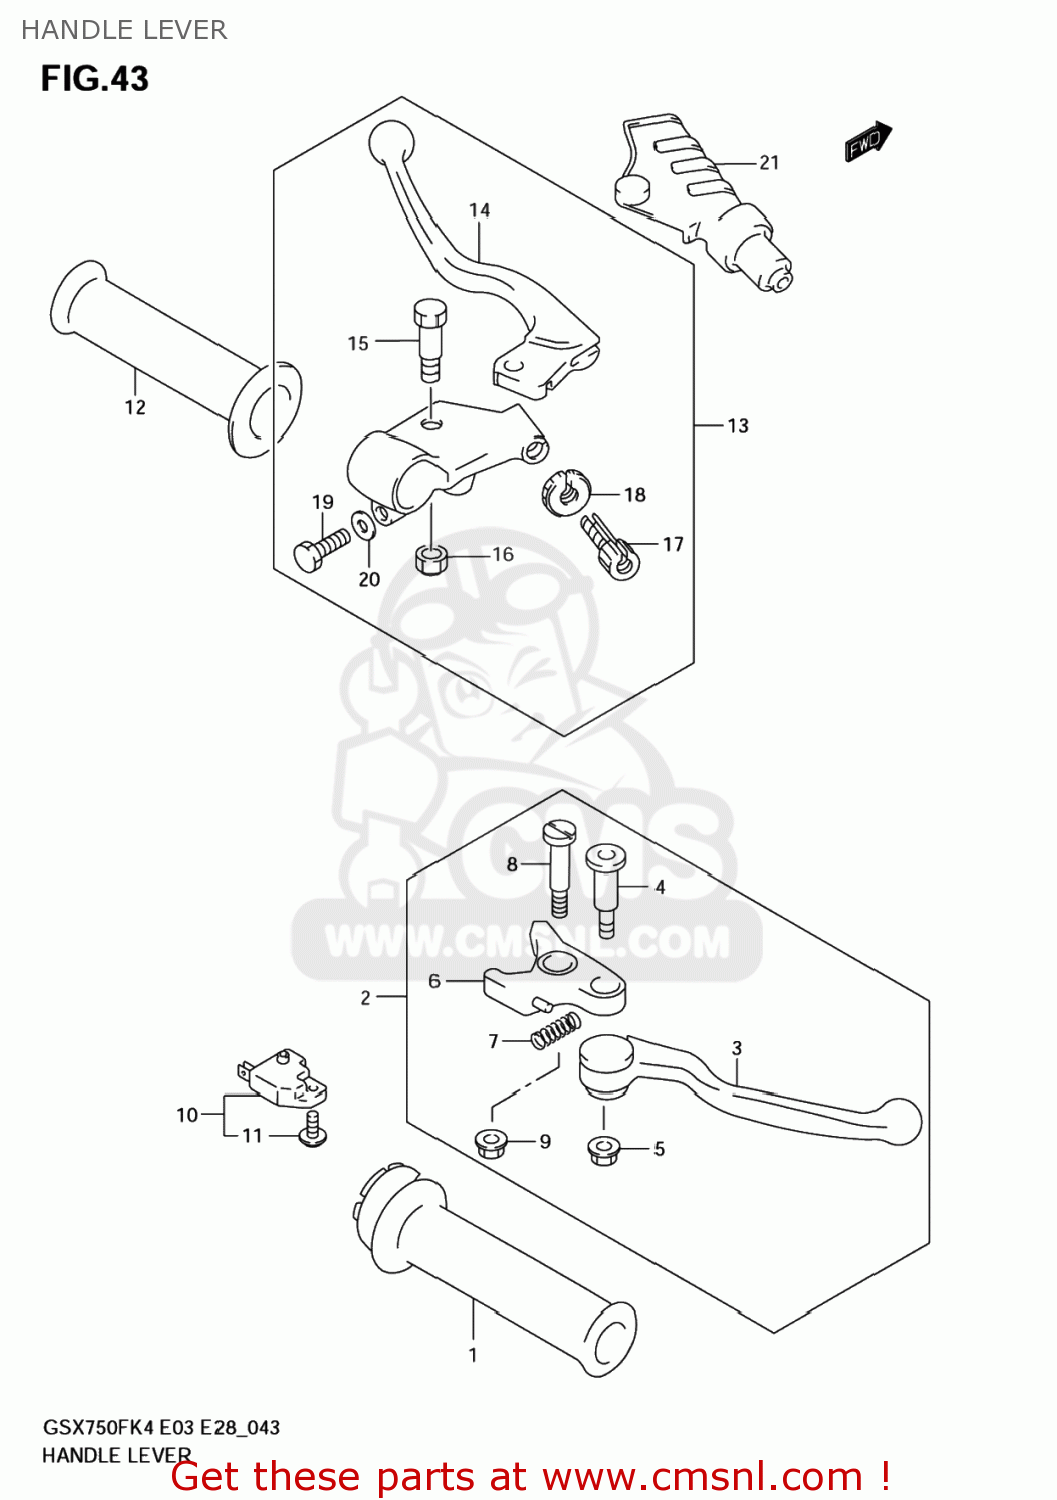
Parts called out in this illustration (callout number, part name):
1	GRIP,THROTTLE
2	LEVER ASSY,BRAKE
3	LEVER,ADJUST
4	BOLT,LEVER
5	NUT
6	RNOCKER
7	SPRING
8	BOLT,LEVER PIVOT
9	NUT
10	SWITCH ASSY,ST
11	SCREW
12	GRIP,LEFT
13	LEVER ASSY,CLUTCH
14	LEVER,CLUTCH
15	BOLT,LEVER SET
16	NUT
17	ADJUSTER,CABLE
18	NUT,CABLE ADJUSTER
19	BOLT
20	WASHER
21	COVER,CLUTCH LEVER
